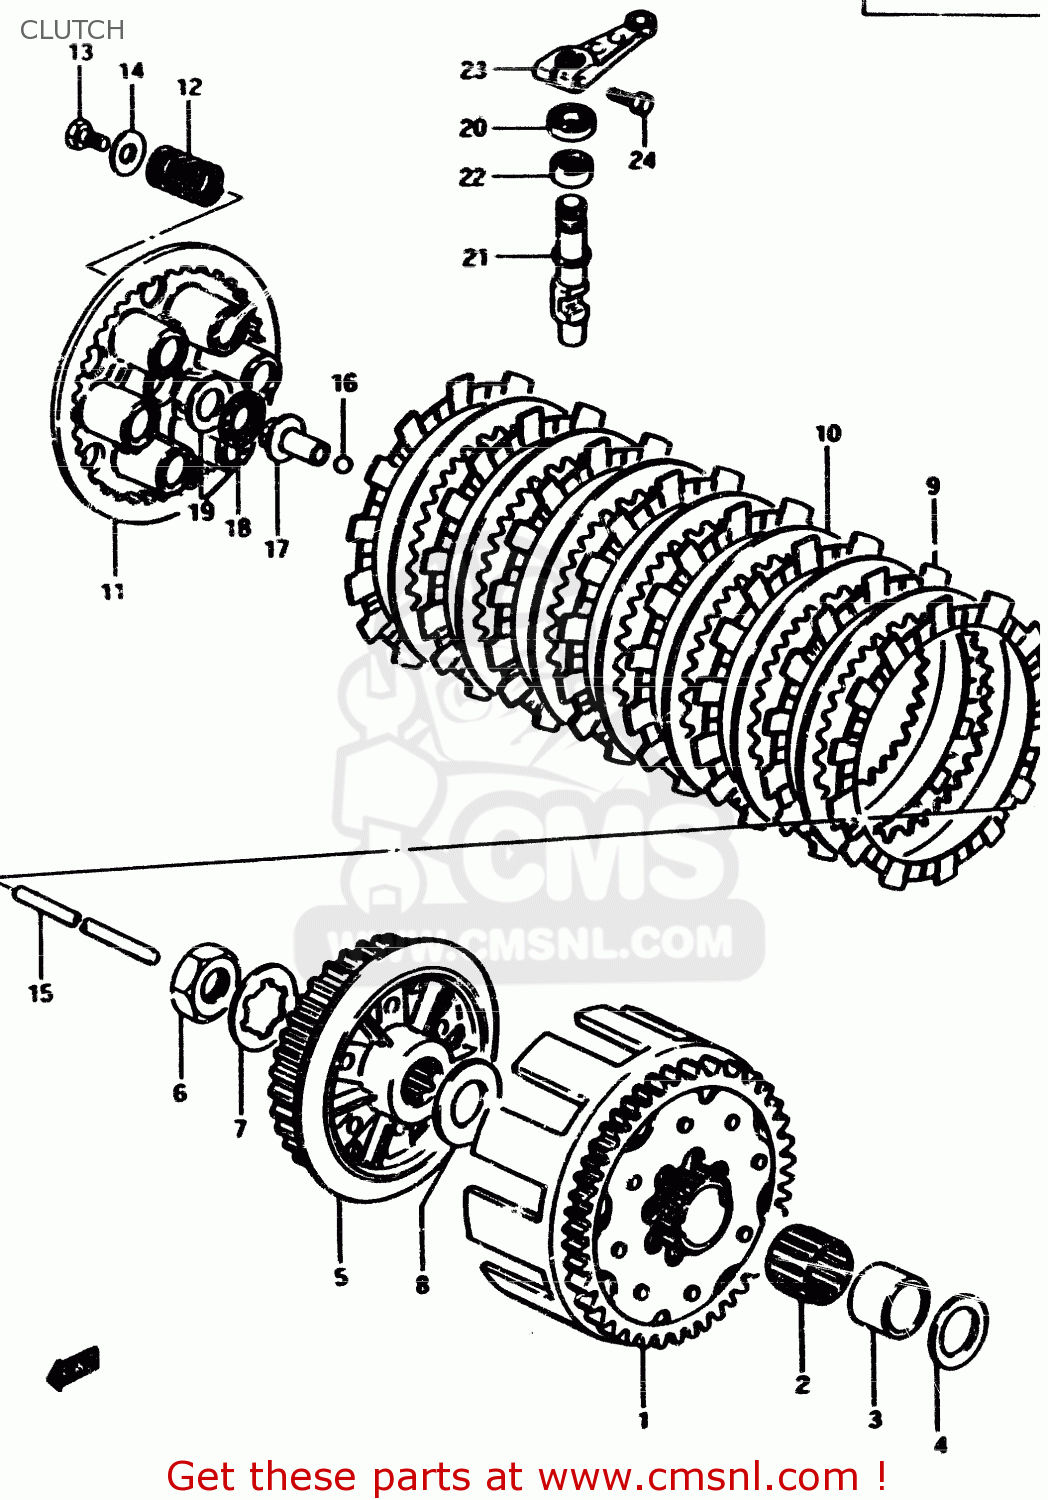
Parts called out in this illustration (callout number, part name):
1	GEAR ASSEMBLY,PRIMARY DRIVE
2	BEARING(28X33X27)
3	SPACER(22X28X27)
4	WASHER
5	HUB,CLUTCH SLEEVE
6	NUT
7	WASHER,LOCK
8	WASHER
9	PLATE,CLUTCH DRIVE (MCA)
10	PLATE,CLUTCH DRIVEN (NAS)
11	DISC,CLUTCH PRESSURE
12	SPRING
13	BOLT, UPPER
14	WASHER
15	ROD,CLUTCH PUSH
16	BALL
17	PIECE,CLUTCH PUSH
18	BEARING(15X28X2)
19	WASHER
20	SEAL,OIL(12X19X5)
21	SHAFT,CLUTCH RELEASE C
22	BEARING(12X19X12)
23	ARM,CLUTCH RELEASE
24	BOLT
